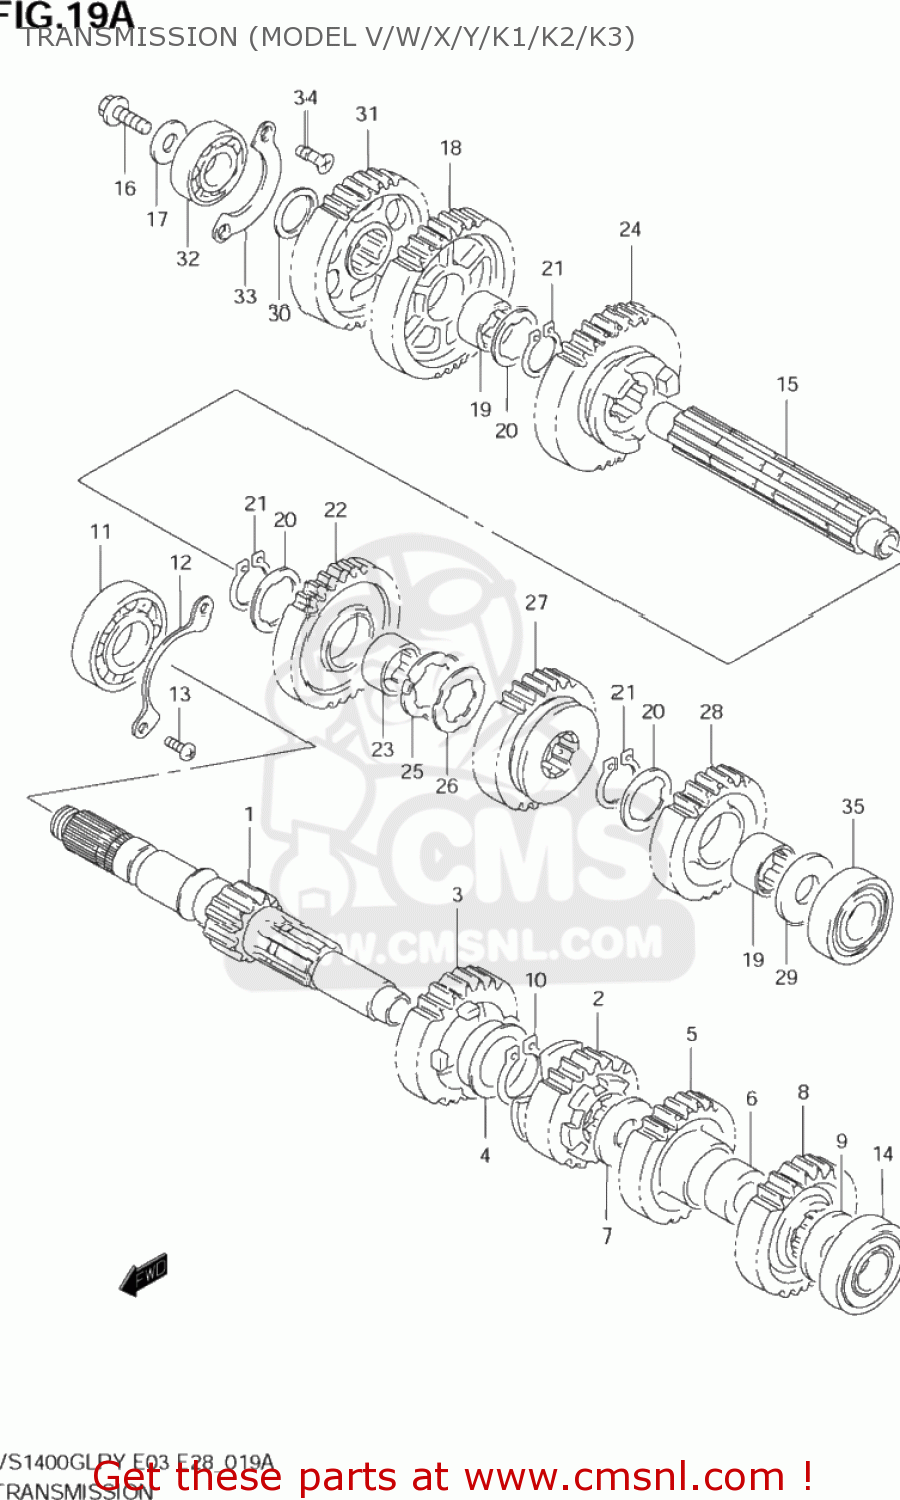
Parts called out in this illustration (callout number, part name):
1	SHAFT,COUNTER
2	GEAR,SECOND DRIVE
3	GEAR,THIRD DRIVE
4	BUSH(28X32X2)
5	GEAR,4TH DRIVE
6	BUSH,4TH DRIVE GEAR
7	SHIM(22X32X1)
8	GEAR,5TH DRIVE
9	SHIM(20X32X1)
10	CIRCLIP
11	BEARING(25X62X17)
12	RETAINER,CNTR SHAFT BEARING
13	SCREW
14	BEARING(20X52X15)
15	SHAFT,DRIVE
16	BOLT(10X24)
17	WASHER
18	GEAR,FIRST DRIVEN
19	BUSH
20	WASHER,LOCK
21	CIRCLIP
22	GEAR,SECOND DRIVEN
23	BUSH,3RD DRIVEN GEAR
24	GEAR,THIRD DRIVEN
25	WASHER
26	WASHER,LOCK
27	GEAR,FOURTH DRIVEN
28	GEAR,5TH DRIVEN
29	WASHER
30	WASHER(22X32X3)
31	GEAR,OVER DRIVING DRIVE(NT:34)
32	BEARING(22X56X16)
33	RETAINER,CNTR SHAFT BEARING
34	SCREW
35	BEARING(20X52X15)
